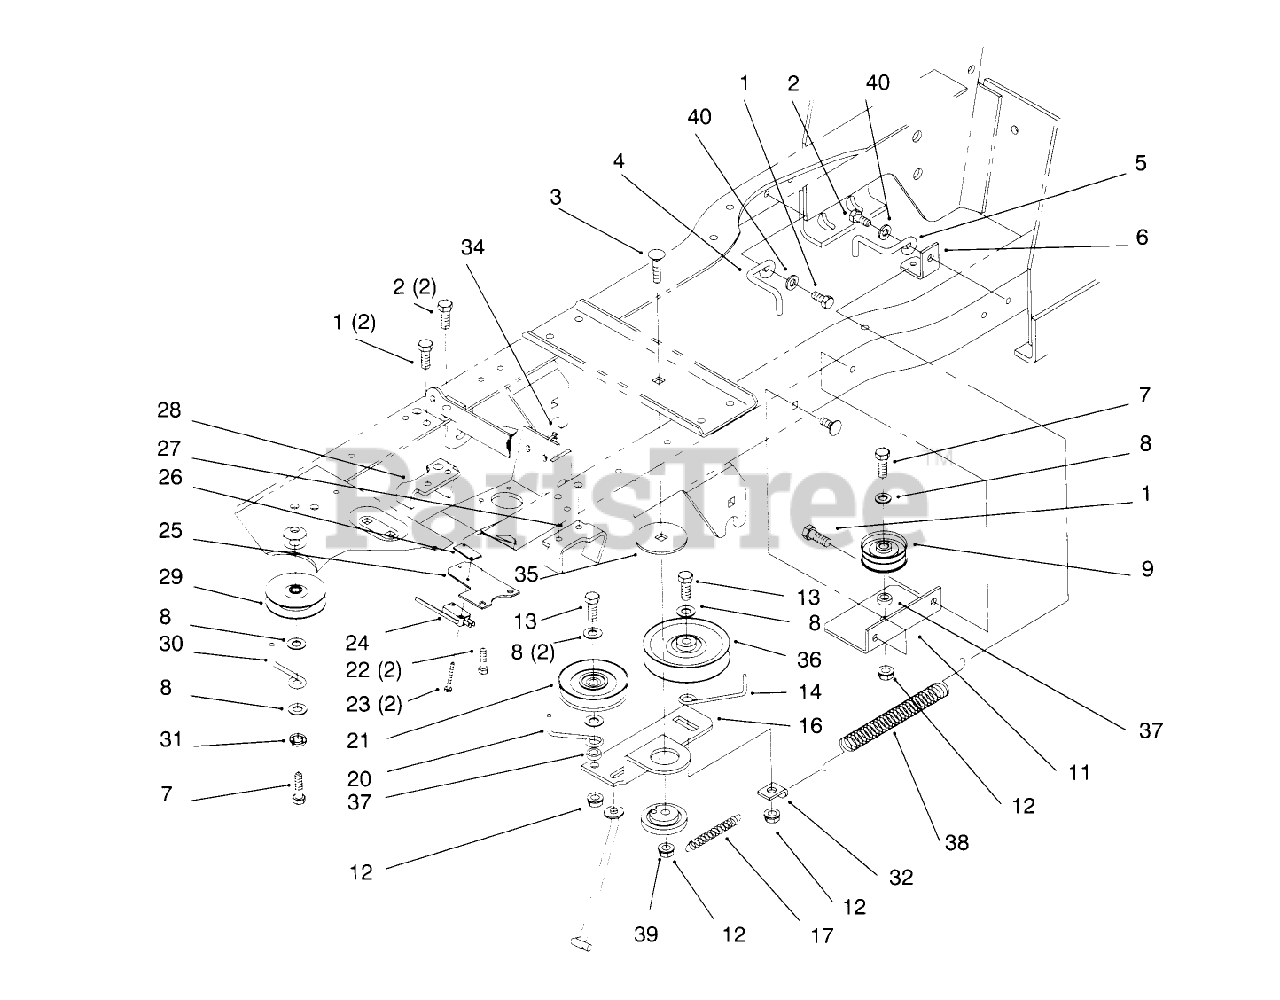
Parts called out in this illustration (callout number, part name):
1	SCREW-HWHTF
2	SCREW-HWHTF
3	BOLT-CARR
7	SCREW-HH
8	WASHER-FLAT
9	PULLEY IDLER NHI
11	BRACKET-REAR IDLER
12	NUT-LOCK, NI
13	SCREW-HH
14	GUIDE-BELT
16	ARM-IDLER
17	SPRING-EXTENSION
20	GUIDE-BELT
21	PULLEY-IDLER
22	SCREW-HWH
24	SWITCH-MICRO
25	BRKT-MICROSWITCH GEAR
26	NUT-SPEED
27	CLUTCH PEDAL STOP
28	BRAKE BRACKET PLATED
29	PULLEY-IDLER
30	GUIDE-BELT
31	WASHER-LOCK
32	CLIP - SPRING
34	TIE-CABLE
35	WASHER-BEARING
36	PULLEY-IDLER, FLAT
37	SPACER
38	SPRING - CLUTCH
39	BUSHING
40	WASHER-PLAIN
